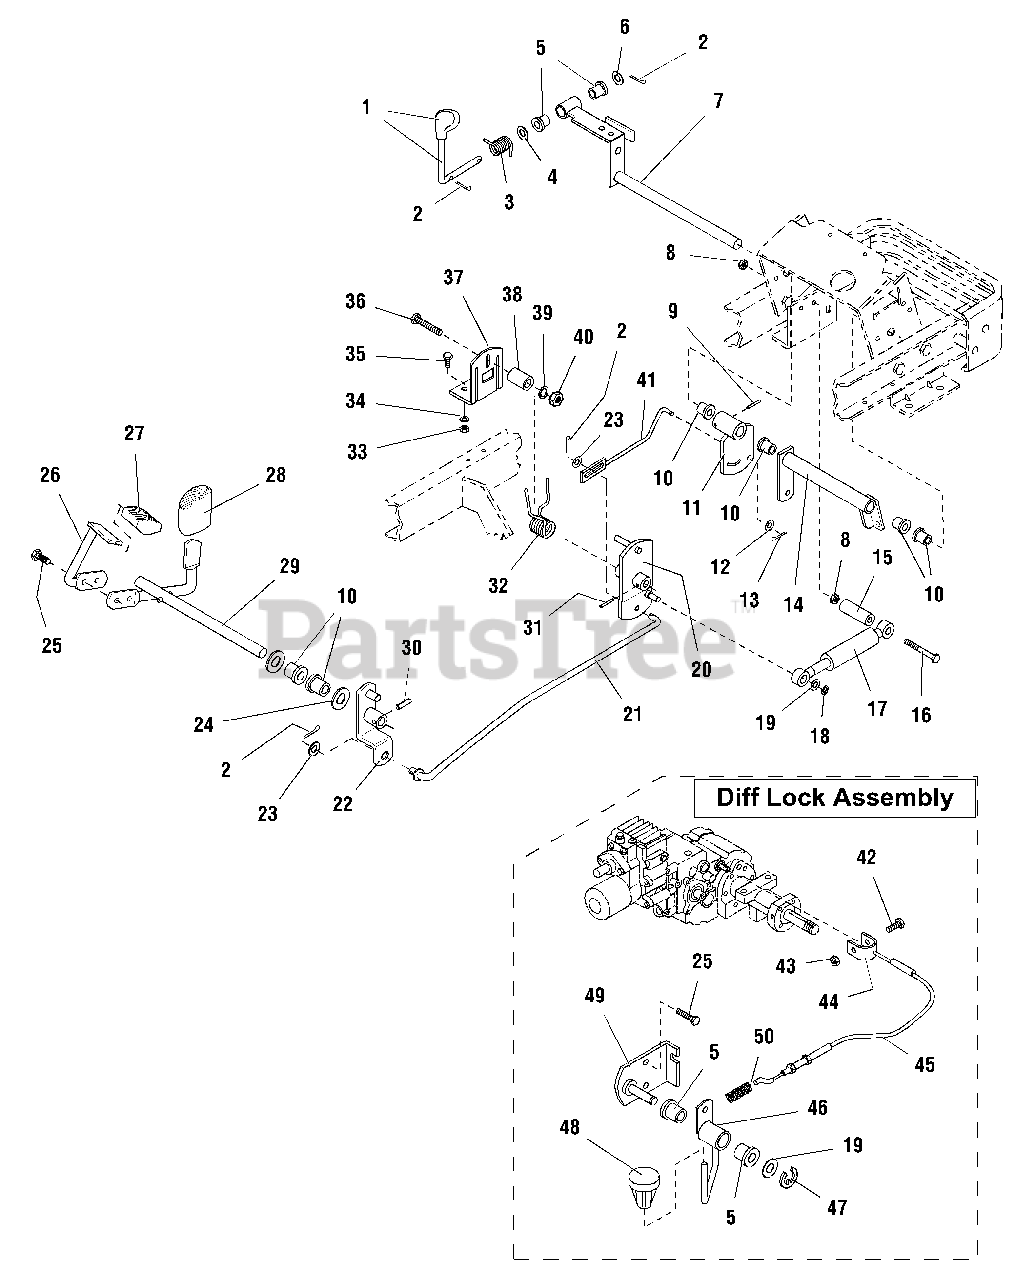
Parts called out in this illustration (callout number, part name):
1	KNOB, Cruise Control
2	PIN, Cotter, 3/32 x 3/4
3	SPRING, Torsion
4	WASHER, 1/2 x 1-1/4
5	BUSHING, Nylon
7	HANDLE ASSEMBLY, Cruise
8	NUT, Hex, Whizlock, 7/16-14
9	PIN, Roll, 1/4 x 1-1/4
11	CONTROL ARM ASSEMBLY, Cruise
12	WASHER, Plain, 3/8
13	PIN, Cotter, 1/8 x 3/4
14	CROSS SHAFT ASSEMBLY, Brake
15	SPACER, Shock Absorber
16	CAPSCREW, Hex Hd, 7/16-14 x 4
17	SHOCK ABSORBER
19	WASHER, Flat, 1/2 x 7/8
20	LEVER ASSEMBLY, Control
21	ROD, Pedal to Lever
22	CONTROL ARM ASSEMBLY
23	WASHER, Plain, 3/8
24	WASHER, Plain, 3/4 x 1
25	CAPSCREW, Hex Hd, Taptite, 5/16-18 x 3/4
26	PEDAL, Foot, Hydro
27	PAD, Pedal (Forward)
28	PAD, Pedal (Reverse)
29	FOOT PEDAL ASSEMBLY
30	PIN, Roll, 1/4 x 1-1/4
31	PIN, Roll, 1/4 x 1-3/4
32	SPRING, Torsion
33	NUT, Hex, Full, 5/16-18
34	LOCKWASHER, 5/16
35	CARRIAGE BOLT, 5/16-18 x 3/4
36	CARRIAGE BOLT, 3/8-16 x 2-1/4
37	PLATE, Pedal Stop
38	TUBE, Neutral
39	LOCKWASHER, 3/8
40	NUT, Hex Jam, 3/8-16
41	ROD, Cruise
42	CAPSCREW, Hex Hd, 1/4-20 x 3/4
43	NUT, Hex, Nylon Lock, 1/4-20
45	CABLE, Diff Lock
46	ARM ASSEMBLY, Diff Lock
47	E-CLIP, Retaining Ring
48	KNOB, Hole, 1/2 x 1-3/4, 2-11/16 Long
49	PIVOT ASSEMBLY, Diff Lock
